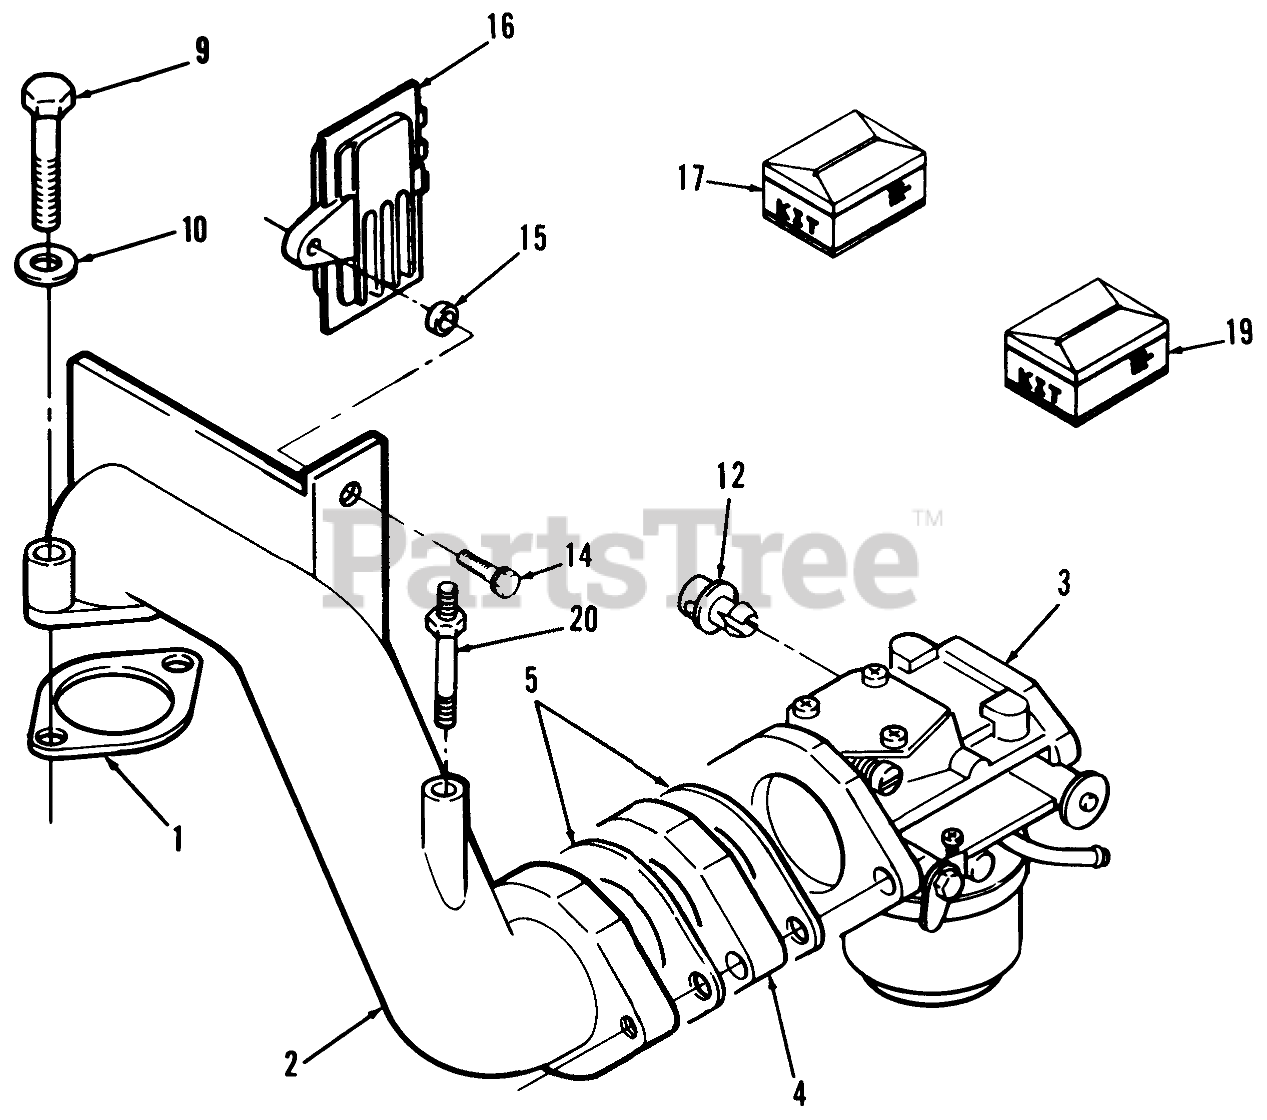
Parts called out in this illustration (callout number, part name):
1	Gasket
2	Elbow-Intake
3	CARBURETOR
4	INSULATOR
5	Gasket
9	SCR-HHC (M8X50)
10	WASHER-FLAT (M8)
12	Clip
14	SCHWH 1/4-20X 7/8 SB
15	Bushing
16	Regulator
17	Regulator
19	CARB-REBUILD KIT
